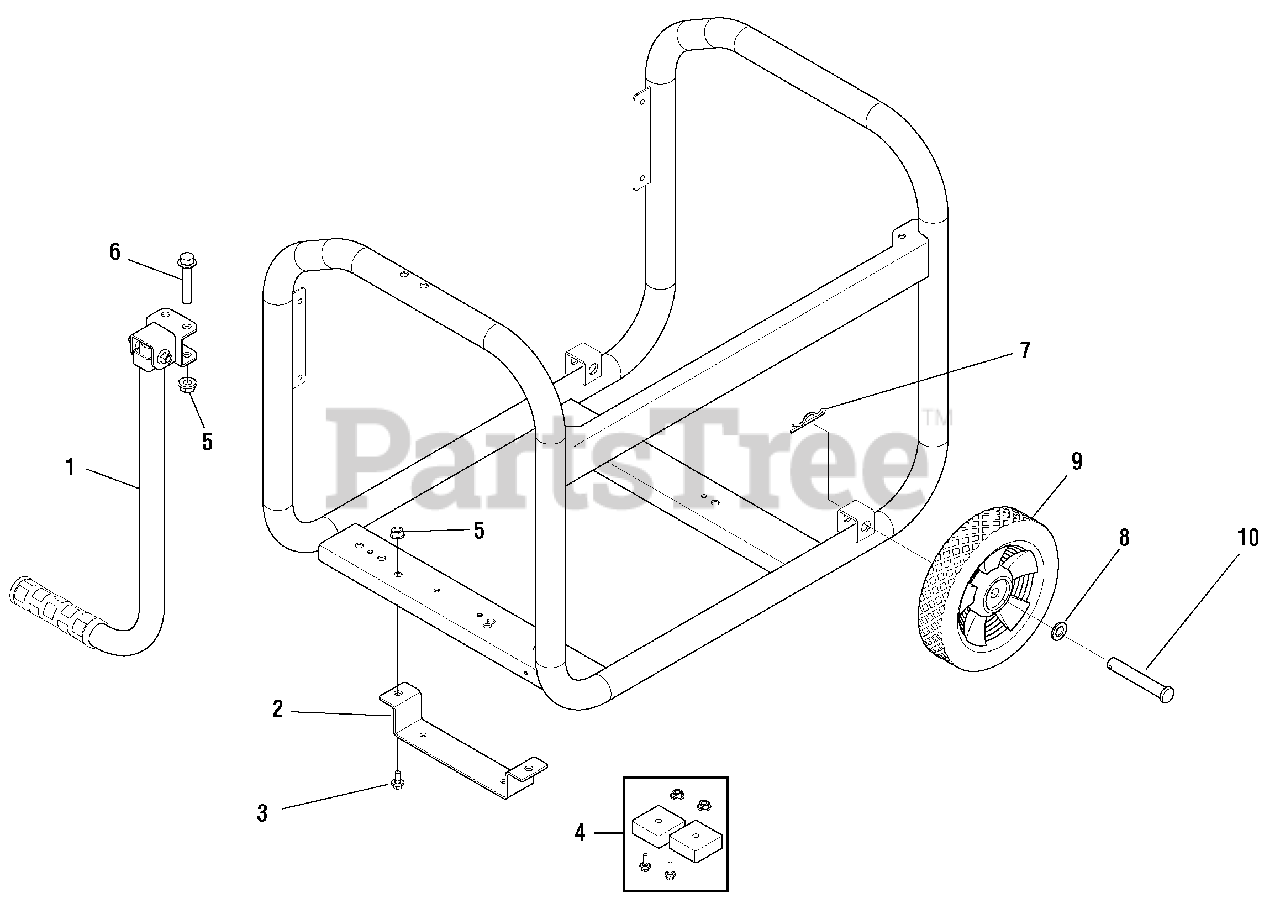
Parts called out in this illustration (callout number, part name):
3	* BOLT, M8-1.25 x 16
4	MOUNT-VIBRATION
5	* NUT, Flange, M8
6	* BOLT, M8 x 80
